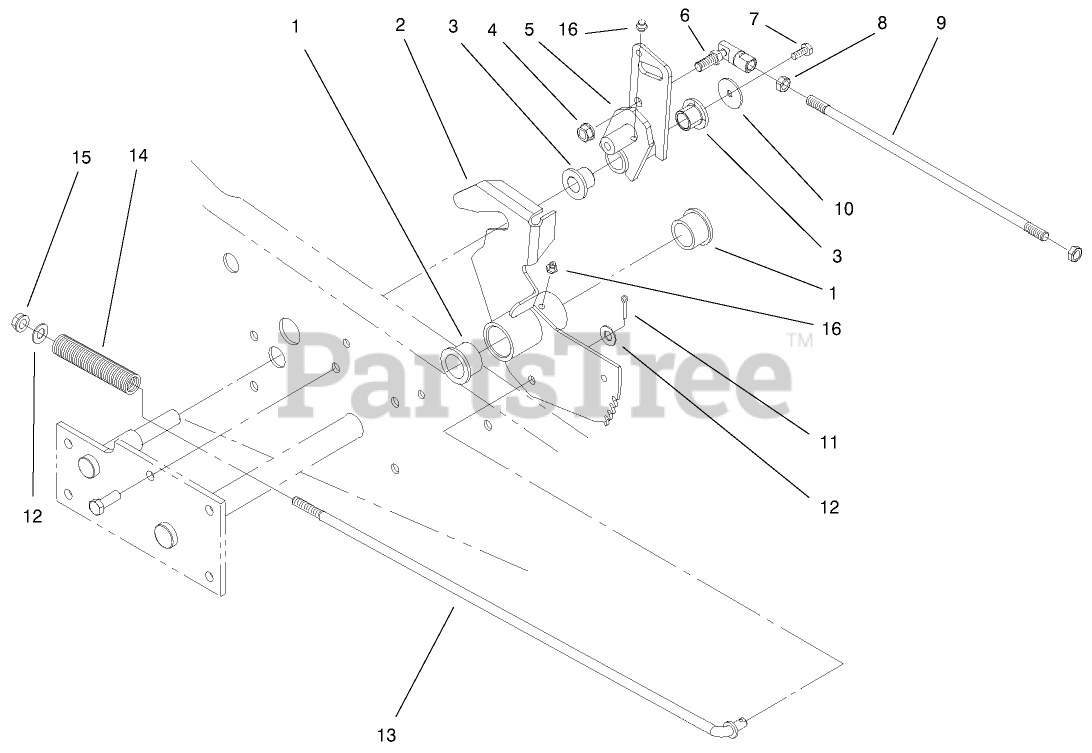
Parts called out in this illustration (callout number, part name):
1	BUSHING-FLANGED
2	PLATE-PIVOT, BRAKE
3	BUSHING
4	NUT-LOCK
5	PIVOT-HYDRO
6	END-TIE ROD, LH
7	SCREW-HH
8	NUT-HEX JAM, LH
9	ROD-PIVOT TO PEDAL
10	WASHER-FLAT
11	PIN-COTTER
12	WASHER-FLAT
13	ROD-BRAKE
14	SPRING-COMPRESSION
15	NUT-LOCK, NI
16	FITTING-GREASE
